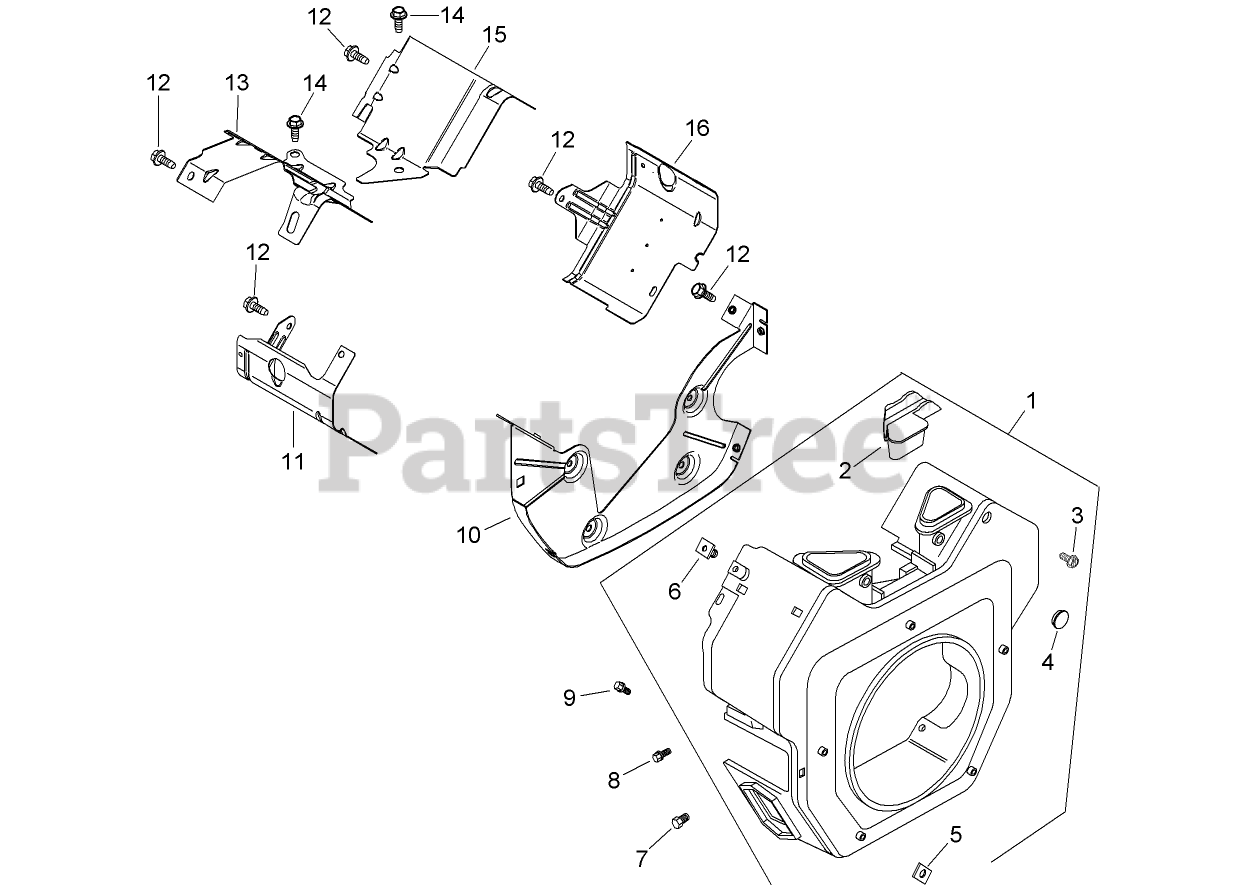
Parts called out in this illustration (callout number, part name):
1	BLOWER HOUSING ASM (INCLUDES 2-6 AND 41 037 10-S)
2	Cover-Housing, Blower
3	Screw-WSH HD Tap (8-18X.50)
4	PLUG-BUTTON (9/16)
5	NUT-PLASTIC
6	Nut-Plastic
7	SCREW-FLANGE, THREAD FORMING (M5X.80X16)
8	SCREW-FLANGE, THREAD FORMING (M5X0.8X16)
9	SCREW-FLANGE, THREAD FORMING (M5X.8X20)
10	PLATE-BACKING (INCLUDES 25 154 11-S)
11	BAFFLE-BARREL, CYL (NO.2 SIDE)
12	SCREW-FLANGE, THREAD FORMING (M6X1.0X16)
13	BAFFLE-VALLEY (No. 2 SIDE)
14	SCREW-HHFTF (M5X.80X10)
15	BAFFLE-VALLEY (No. 1 SIDE)
16	BAFFLE-BARREL, CYL (NO.1 SIDE)
